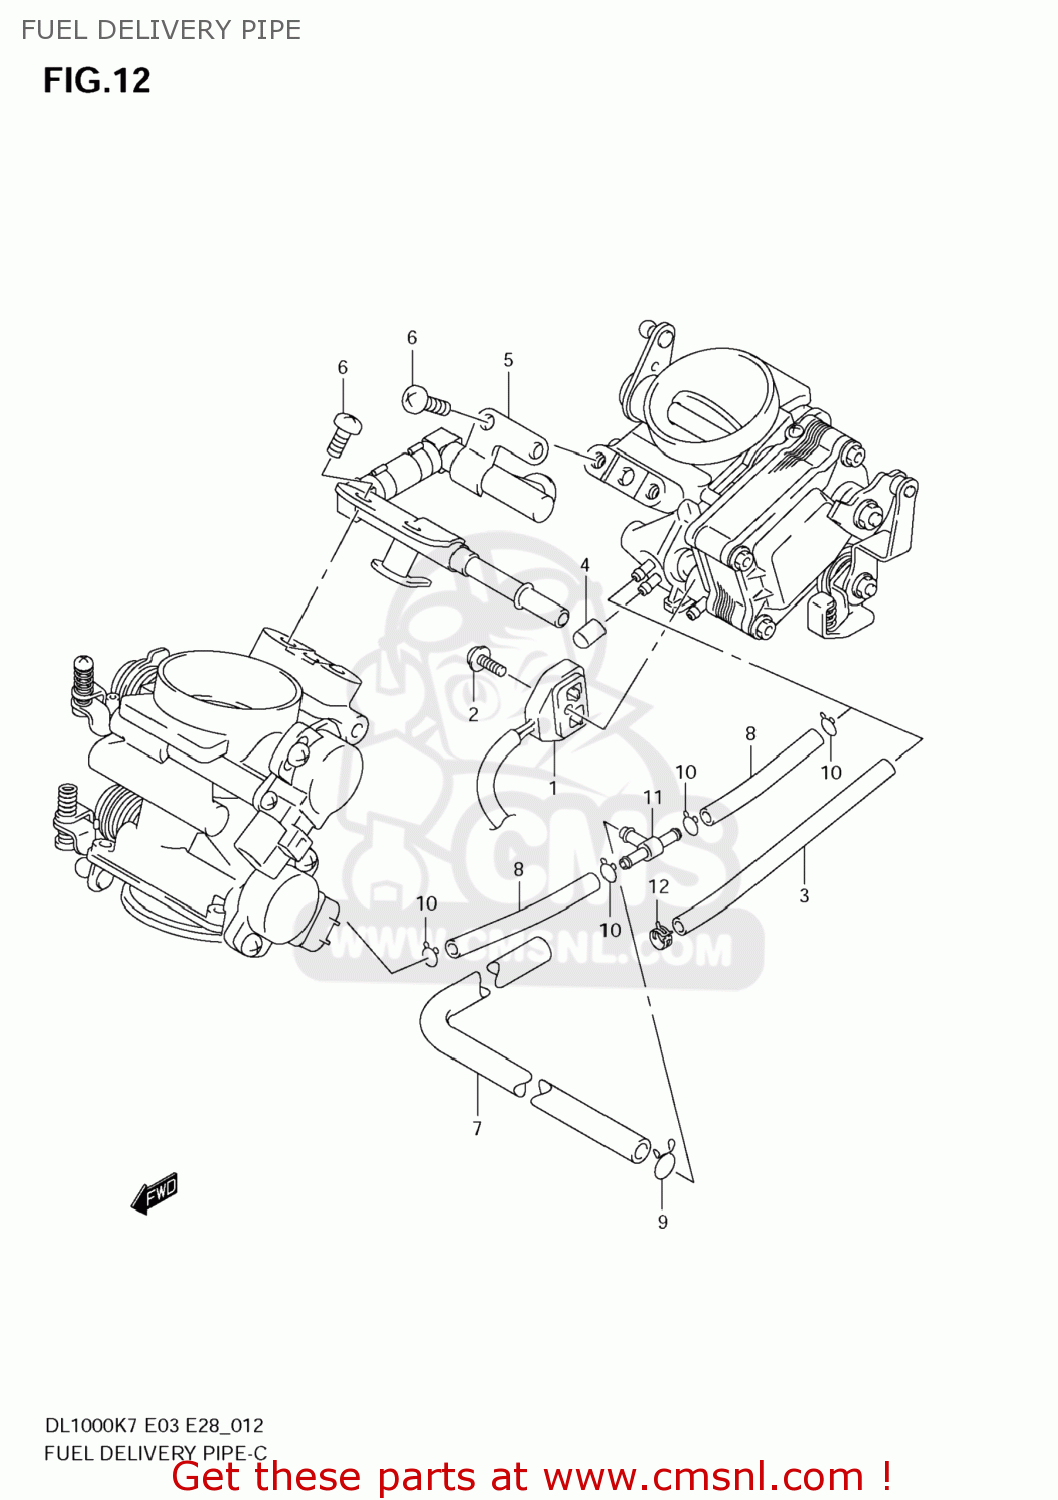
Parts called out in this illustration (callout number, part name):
1	HARNESS ASSY
2	SCREW
3	HOSE(L:425)
4	CAP
5	DELIVERY PIPE ASSY
6	SCREW
7	HOSE
8	HOSE
9	CLIP
10	CLIP
11	NIPPLE
12	CLIP
